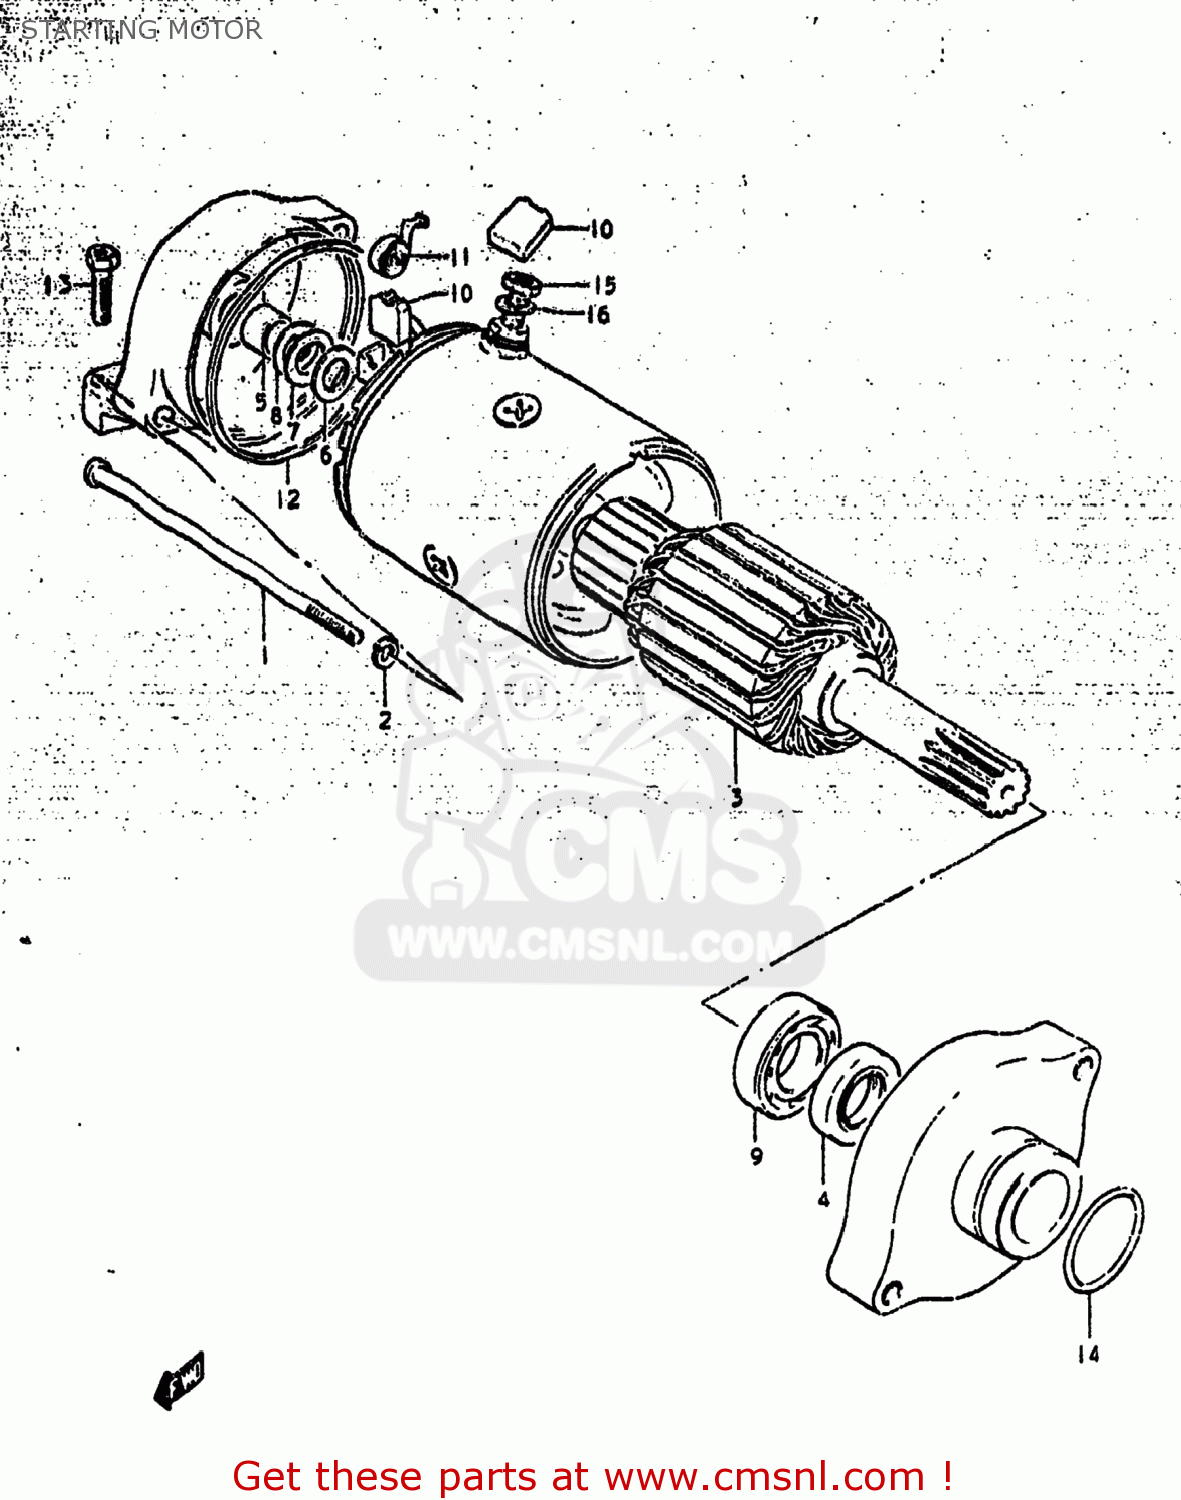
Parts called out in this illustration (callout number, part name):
1	BOLT
2	LOCK WASHER
3	ARMATURE
4	SEAL,OIL
5	BUSHING
6	SHIM, (1)
7	SHIM, (2)
8	SHIM, (3)
9	BEARING
10	BRUSH(-)
11	SPRING
12	GASKET
13	SCREW
14	O RING(D:2,ID:24.5)
15	NUT 6MM
16	LOCK WASHER
